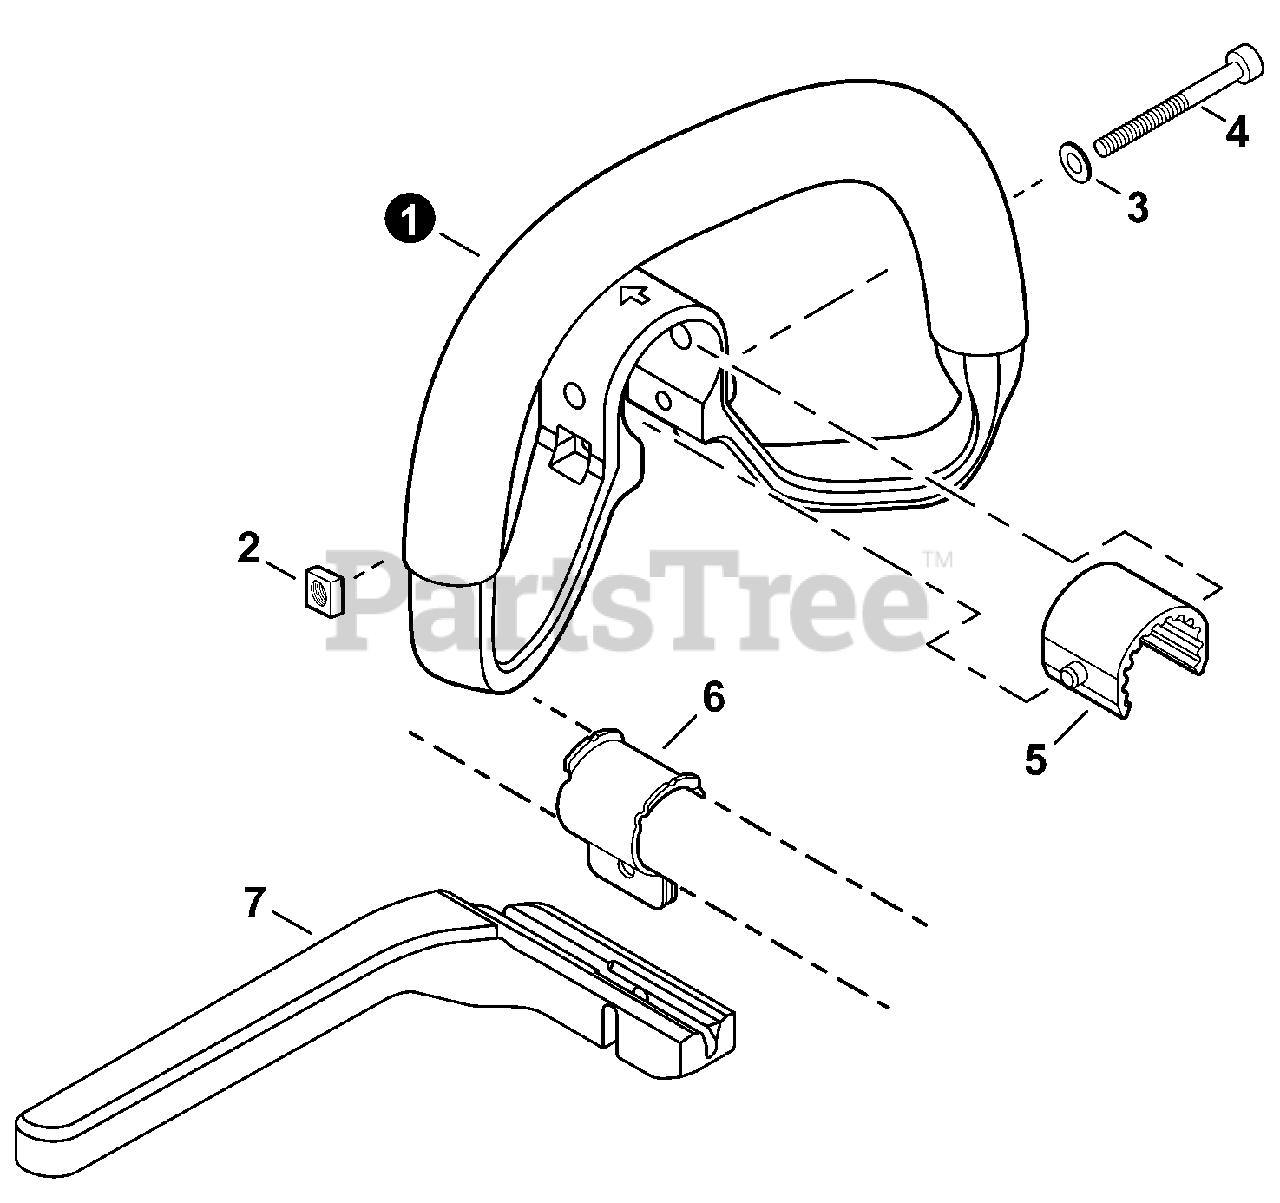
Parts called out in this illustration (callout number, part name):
1	HANDLE, SUPPORT
3	WASHER 5.5x12x0.8
4	BOLT, TORX 5x40
5	CUSHION
6	BRACKET, MOUNTING
7	BAR, BARRIER
